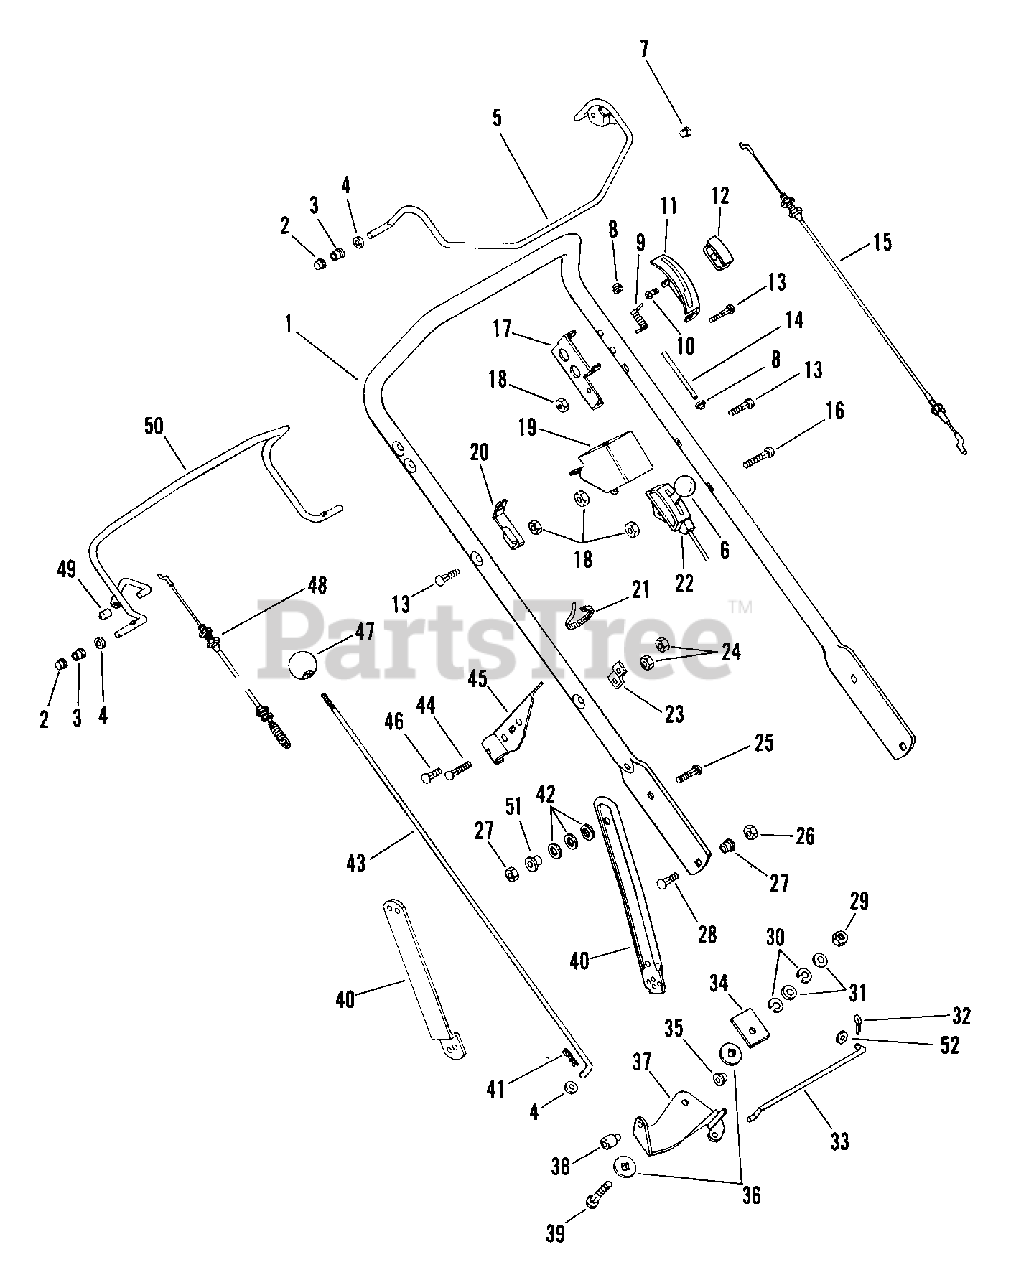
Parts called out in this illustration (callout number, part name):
1	HANDLEBAR
2	NUT-PUSH .312 DIA. PAL
3	BSHG-FLG .325X.444X.440X.560
4	WSHR-FL-STL.344X.688X.065PL
5	START BAIL WELDMENT
5	BBC BAIL WELDMENT
6	KNOB, CONTROL-THROTTLE
7	PUSH NUT, .25
8	PUSH NUT, .188
9	SG-TORS .062X.28X1.00
10	SCR-TAP 10-24X.375 CRPH PL 1A
11	BBC LATCH
12	KNOB
13	BLT-RDHDSQNK .25-20X1.25 XLGPL
14	PIN,BBC LATCH
15	CABLE,ENGINE
15	CABLE-ENGINE CONTROL
15	CABLE-BBC
16	BLT-RDHDXLSQNK .25-20X2.0 G5YZ
17	BBC LATCH PIVOT
18	NUT-KEPS .250-20
19	SWITCH-CABLE ANCHOR
20	CABLE ANCHOR
20	CABLE ANCHOR-LH
21	CABLE TIE LG 5-1/2
22	CABLE THROTTLE NEGATIVE ACTION
23	BRACE-SPEED CONTROL
24	NUT-LK-CTR .250-20 PL
25	BLT-RDHDSQNK .31-18X1.12 GR5PL
26	NUT-LK-TOP .312-18 GR C PL
28	BLT-RDHDSQNK.31-18X.88 GR5YWZC
29	NUT-LK-CTR .375-16 GR A PL
30	WSHR-LK .375X.115 HVY PL
31	WSHR-FL-STL.406X.812X.065PL
32	PIN-COTR .06X.50
33	SHIFT LINK
34	PRESSURE FLANGE
35	CAP, 3/8 ROD YWZC
36	FRICTION WASHER
37	BELL CRANK - SPEED CONTROL
38	SWIVEL
39	BLT-RDHDSQNK .38-16X1.50 PL
40	LINK,HANDLE BAR ADJUST LH
40	LINK,HANDLE BAR ADJ RH
41	PIN-HAIR INT .08X.18X1.18
42	WASHER,BELLEVILLE SPRING
43	ROD-SPEED CONTROL
44	BLT-RDHDSQNK .25-20X1.38SHT PL
45	BRACKET-SPEED CONTROL
46	@BLT-RHDSSQNK .25-20X.38 G2YZ
47	KNOB, BALL 5/16-18 X 1.5
48	CABLE, TRACTION
49	CAP, VINYL, .25 ID
50	TRACTION BAIL-COATED
51	BSHG-FLG .325X.500X.513X.875
52	WSHR-FL-STL.281X.62X.065 PL
